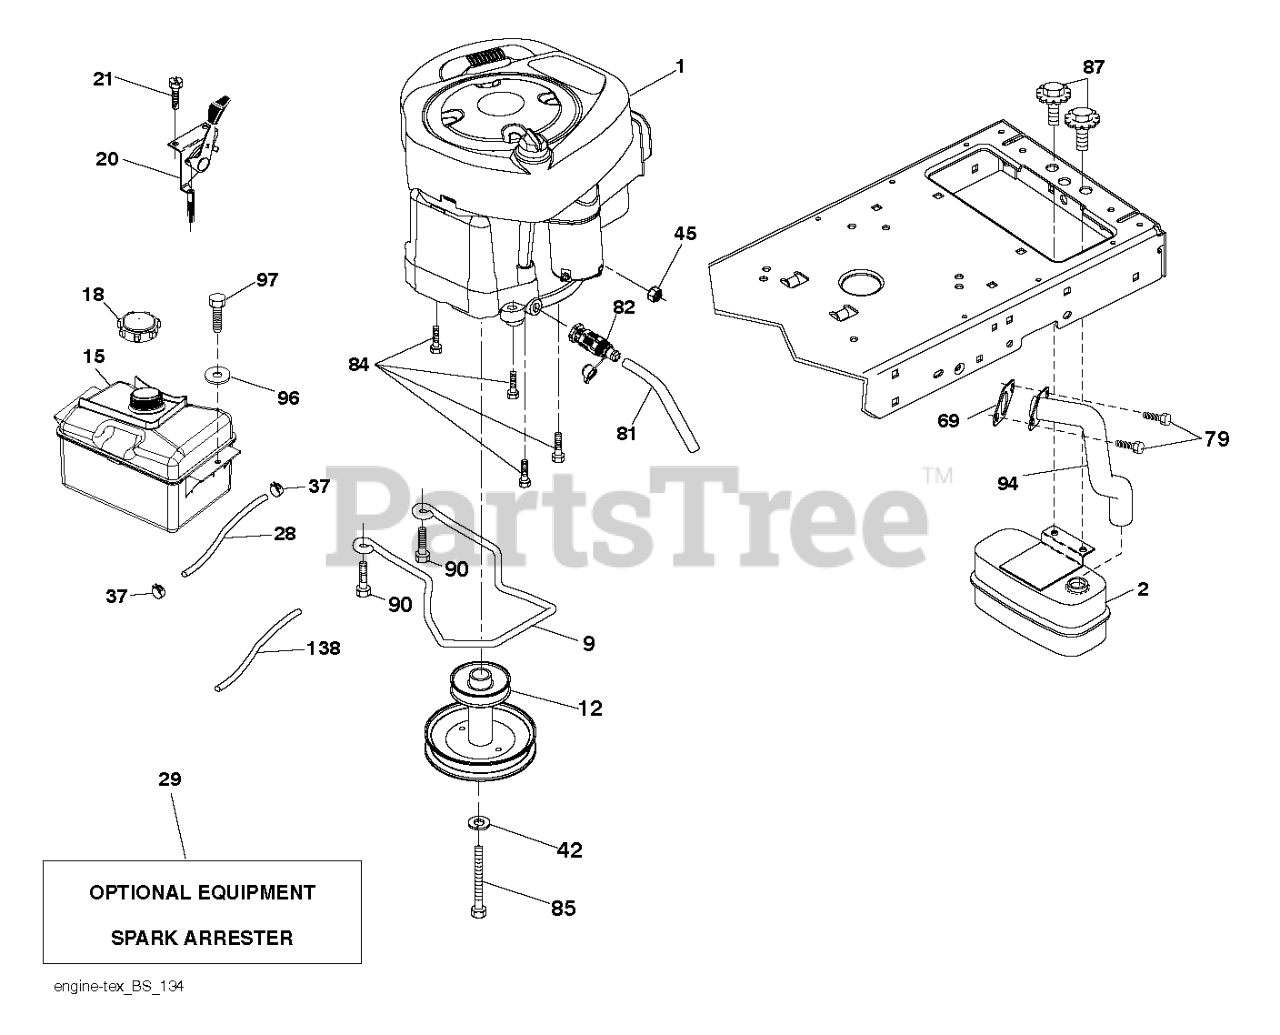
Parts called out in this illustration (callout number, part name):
2	MUFFLER.ASM.SINGLE
9	KEEPER.BELT.ENG.4.25"2.BLT.431
12	PULLEY.ENGINE
15	TANK.ASM.FT.2.5GAL.W/CAP.EPA17
18	CAP.FUEL.2 WAY VENT
20	CONTROL.TH/CK.C.
21	SCREW.#10 X 0.750.BOS (2 2)
28	LINE.FUEL.20"FRONT.EMI
29	Arrester, Spark (Optional equipment) (AYP part number)
37	Clamp Hose Black (AYP part number)
42	WASHER 7/16 LOCK
45	Nut Keps Hex 1/4 - 20 UNC (AYP part number)
69	GASKET.MUFFLER
79	SCREW.SOCKET HD.5/16-1
81	TUBE, DRAIN OIL ASM.
82	VALUE.OIL.DRAIN
84	SCREW.3/8-16
85	Speed Clip
87	BOLT, 5/16-18 X 1 3/4
90	SCREW 3/8-16X1
94	EXHAUST.TUBE.B&S.28/31
96	Washer 9/32 x 7/8 x 16 Gauge (AYP part number)
97	SCREW HEXWSHR 1/4-20X3/4
138	RP PURGE LINE
